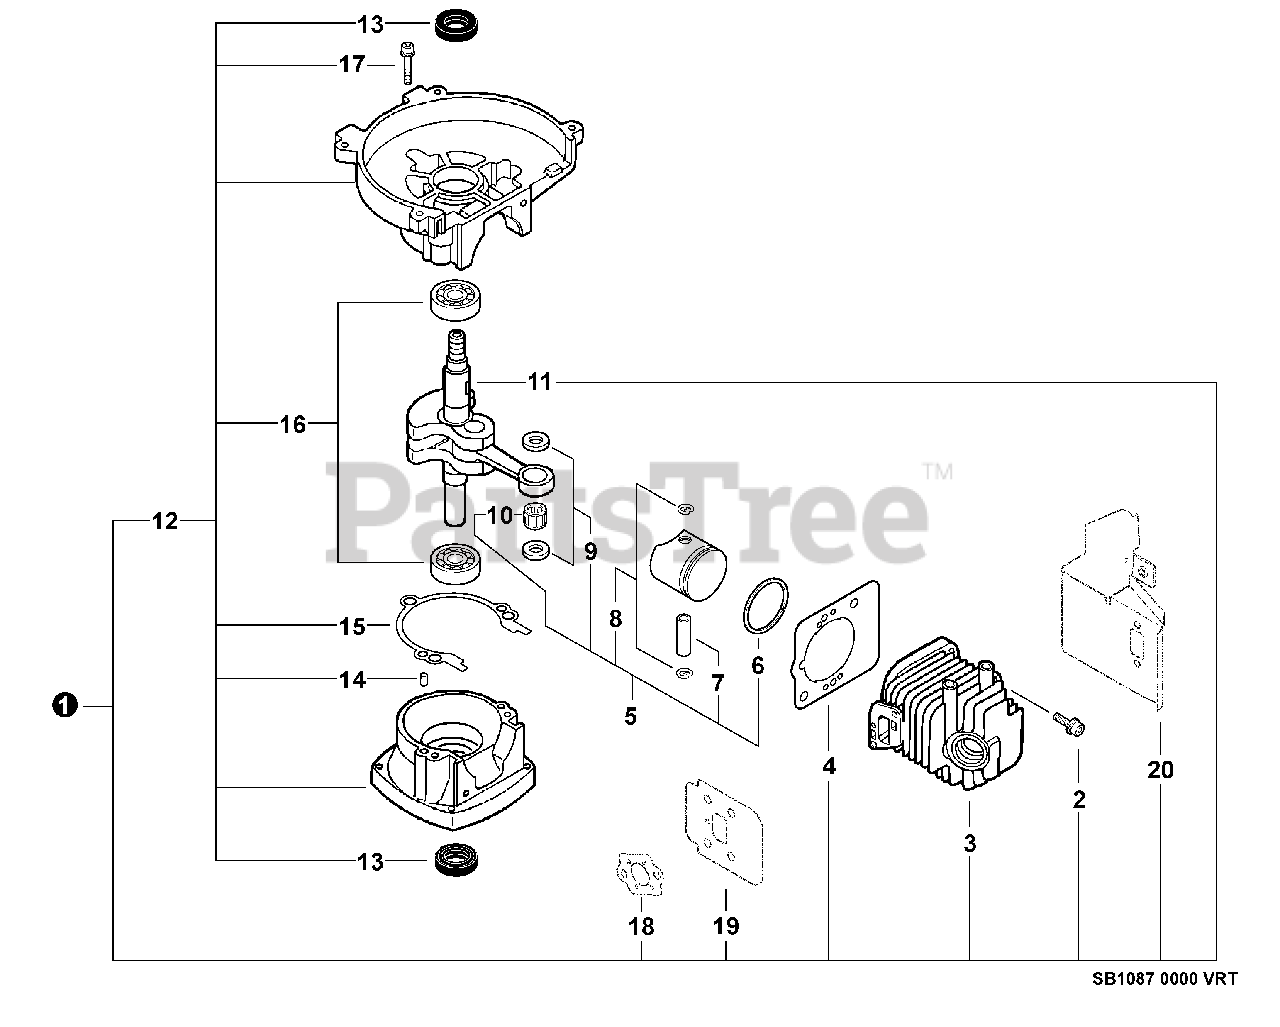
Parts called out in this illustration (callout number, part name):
1	SHORT BLOCK
2	BOLT 5×22
3	CYLINDER
4	GASKET, CYLINDER
5	PISTON KIT
6	RING, PISTON
7	PIN, PISTON 8
8	RING, SNAP
9	WASHER, THRUST
10	CRANKSHAFT ASSY
11	BEARING, NEEDLE 8
12	CRANKCASE KIT
13	SEAL, OIL 12
14	PIN, LOCATING 4
15	GASKET, CRANKCASE
16	BEARING, BALL - 6201 C3
17	BOLT 5×28
18	GASKET, INTAKE
19	SHIELD, INTAKE
20	SHIELD, EXHAUST
